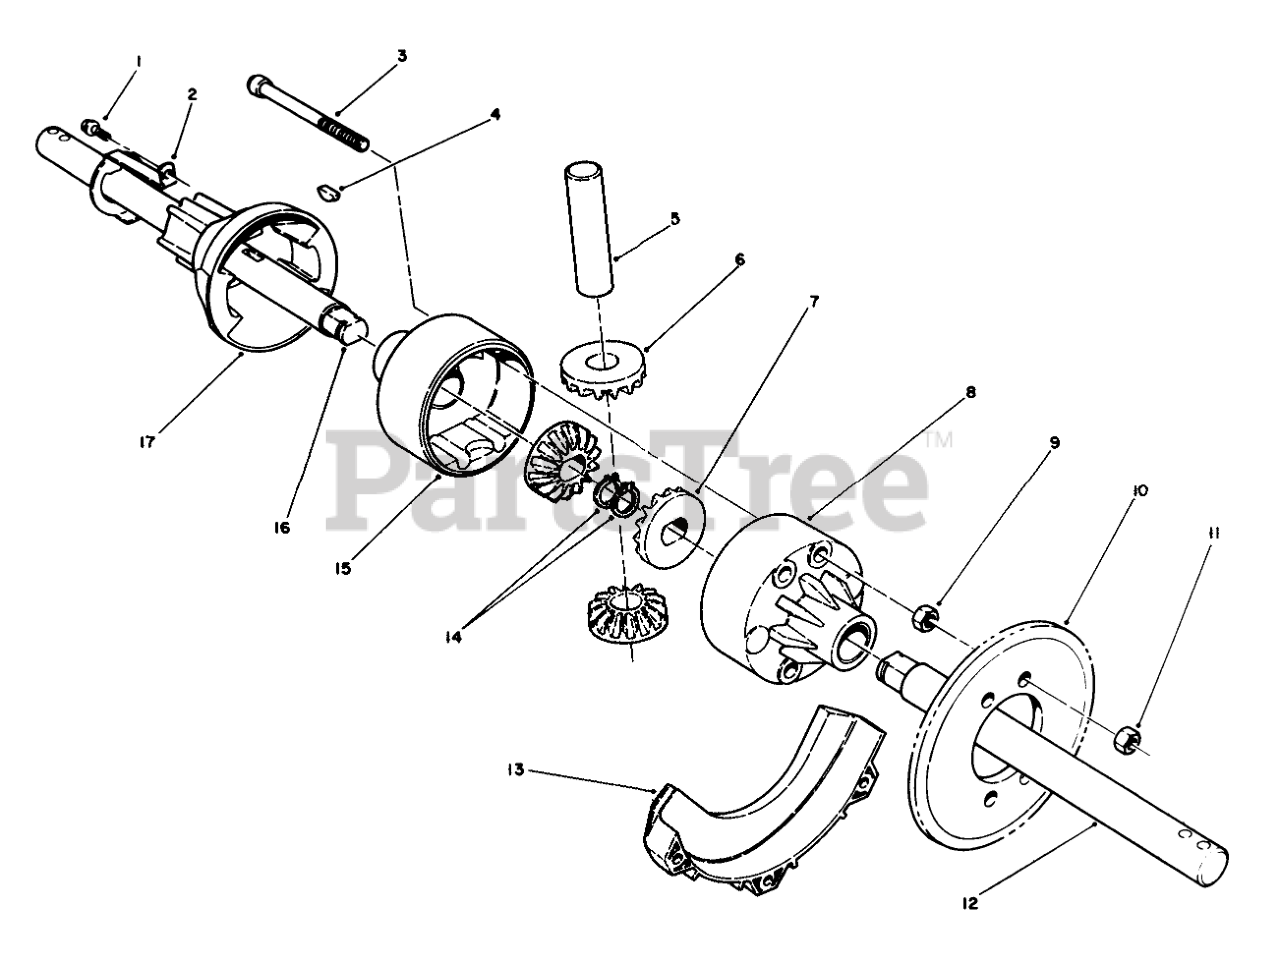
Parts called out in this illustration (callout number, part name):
1	SCREW-HWH
2	SPRING-LOCKOUT
3	SCREW-HSH
4	KEY-WOODRUFF
5	Shaft-Cross
6	Gear-Cross Shaft Pinion
7	Gear-Side Pinion
8	HOUSING ASSY - FEMALE
9	NUT-HEX
10	SPROCKET-27T
11	NUT-LOCK, NI
12	SHAFT - DIFFERENTIAL,LH
13	GUARD-CHAIN
14	RING-RETAINING
15	HOUSING ASSY - MALE
16	SHAFT - DIFFERENTIAL,RH
17	COUPLING-DIFFERENTIAL
